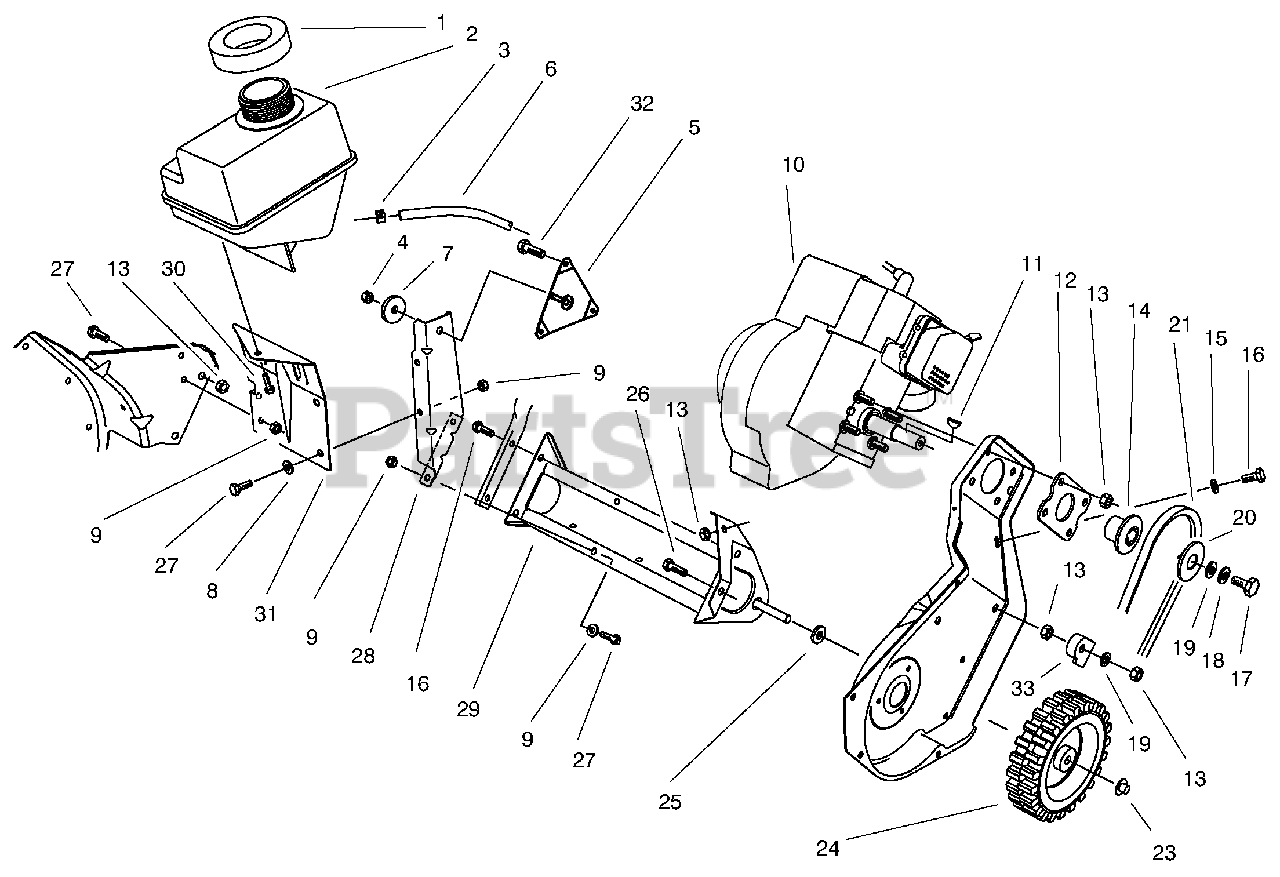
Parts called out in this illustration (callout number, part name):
1	Seal-Fuel Tank
2	Tank-Fuel
3	Clamp-Hose
4	Nut-Lock
5	Bracket-& Stud Assembly
6	Hose-Fuel
7	Washer-Engine Support
8	Washer-Flat
9	Nut-Lock
11	Key-Woodruff
12	Plate-Engine
13	Nut-Lock
14	Hub-Sheave
15	Washer-Flat
16	Screw-Hex. Hd.
17	Screw-Locking Hex. Hd.
18	Washer-Belleville
19	Washer-Flat
20	Cap-Sheave
21	Belt-Drive
25	Spacer-Wheel
26	Screw-Hex. Hd.
27	Screw-Hex. Hd.
28	Support-Engine
29	Frame Assembly
30	Screw-Thread Forming
31	Bracket-Fuel Tank
32	Screw-Thread Form.
33	Guide-Cable
